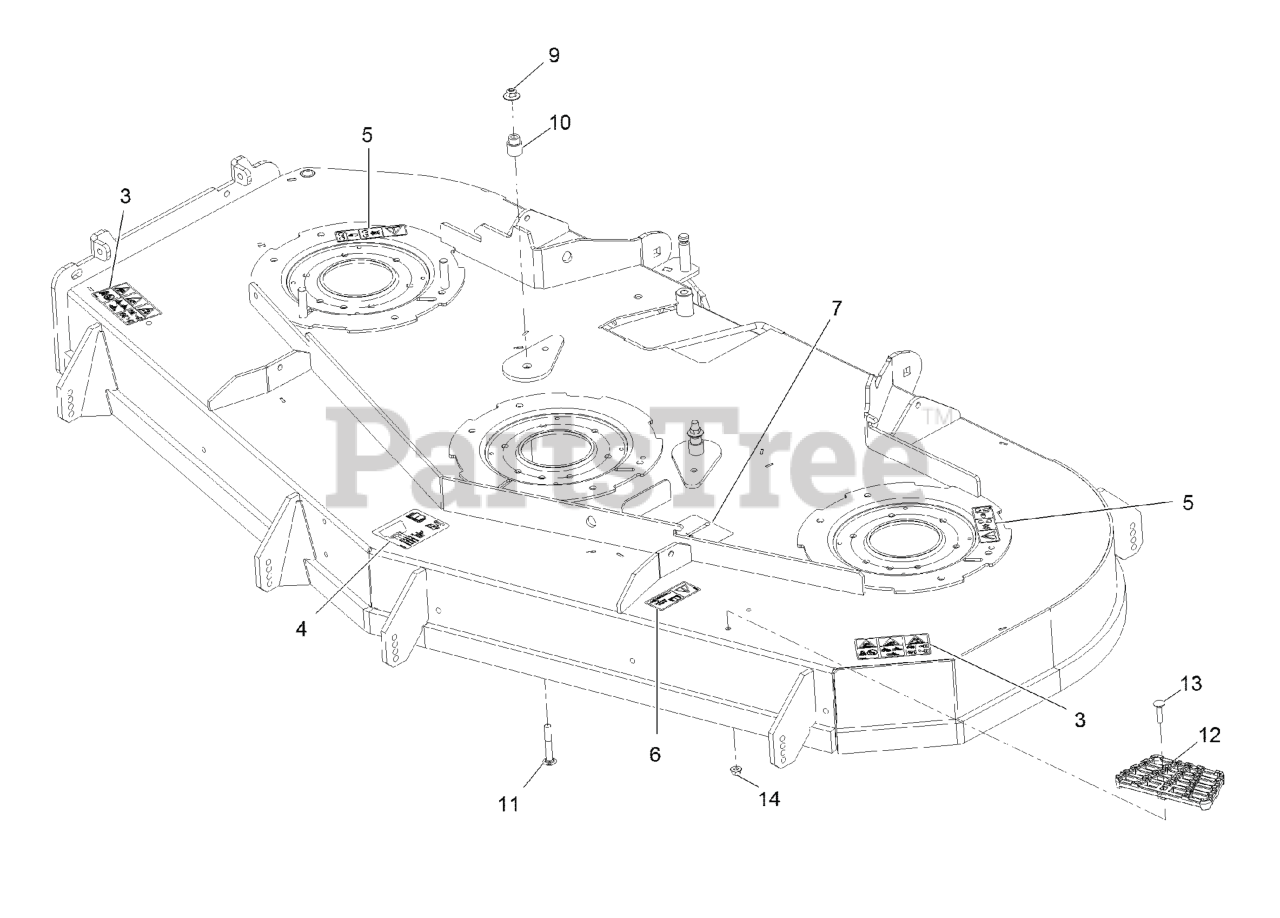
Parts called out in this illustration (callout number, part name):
3	DECAL-DANGER THROWN OBJECTS
4	DECAL-ROLLER, ANTI-SCALP
5	DECAL-COVER, MISSING
6	DECAL-TORQUE, BOLT
7	DECAL-BELT ROUTING
9	Nut-Nyloc 3/8-16 Flg
10	BUSHING-IDLER
11	SCREW-CARR
12	STEP-DECK
13	Bolt-Carriage 5/16-18 X 1 1/4
14	NUT-HF, NI
